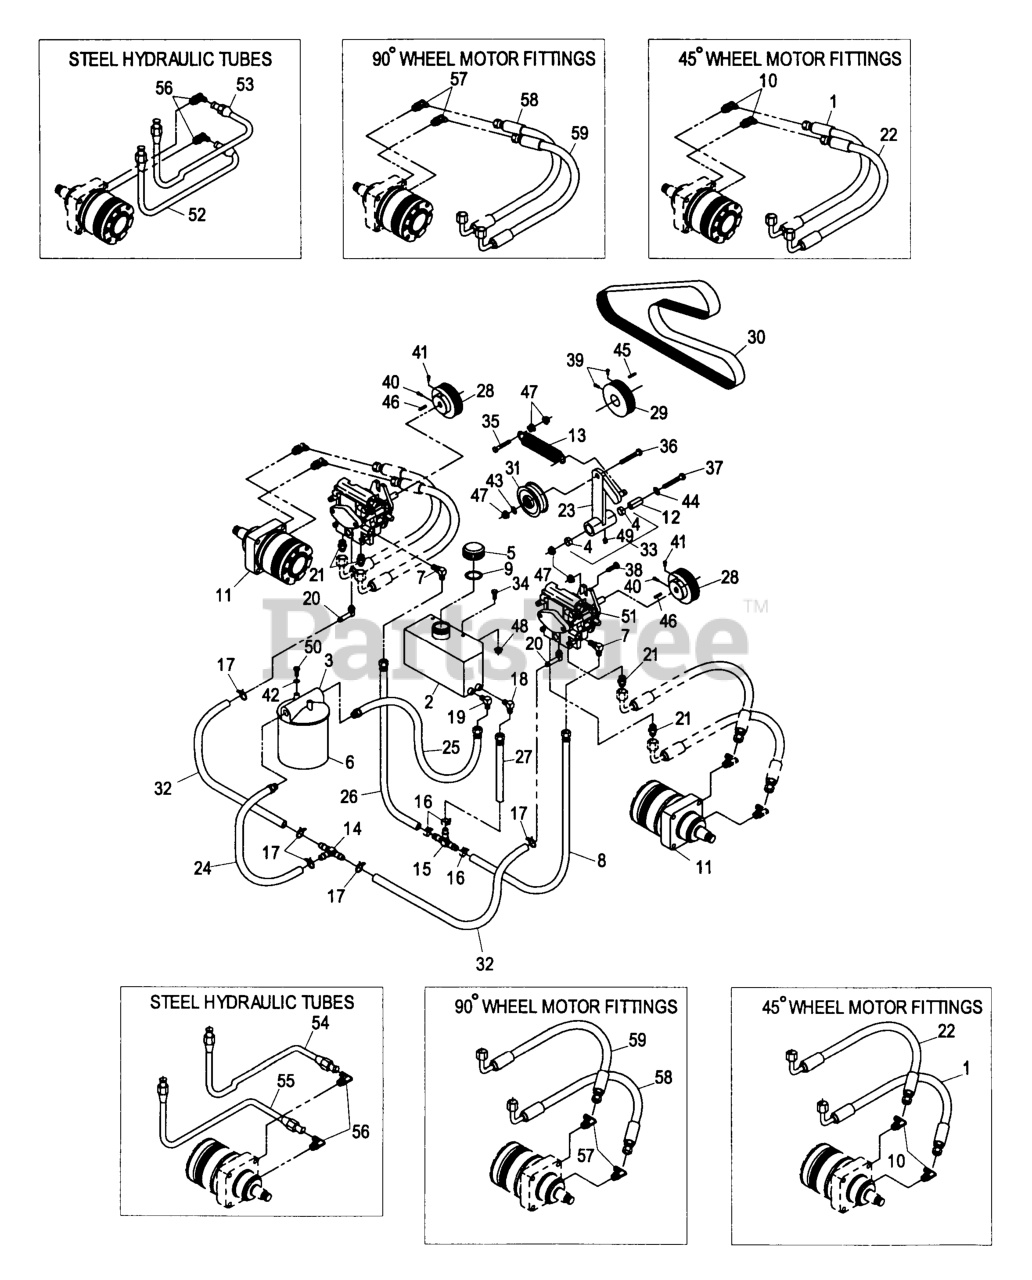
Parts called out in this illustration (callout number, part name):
1	HOSE-PRESSURE, HIGH
3	FILTER-HEAD
4	SLEEVE-BEARING
7	FITTING-90 DEG
8	LOW PRESSURE HOSE ASM
9	GASKET-CAP, TANK
10	FITTING-HYD, 45 DEG
11	MOTOR-WHEEL
12	BUSHING-PIVOT, IDLER
13	SPRING-EXTENSION
14	FITTING-TEE, HOSE
15	FITTING-TEE, HOSE
16	CLAMP-HOSE
17	CLAMP-HOSE
18	FITTING-ELBOW
19	FITTING-ELBOW
20	FITTING
21	FITTING-STRAIGHT
24	HOSE ASM
25	HOSE ASM
26	HOSE ASM
27	HOSE ASM
30	BELT,POLY-V 5K
31	SHEAVE-IDLER
32	HOSE-PRESSURE, LOW
33	BEARING ARM ASM
37	SCREW-HH
39	SCREW-SET
41	SCREW-SET
42	WASHER-LOCK
52	TUBE, RH LOWER 52"
53	TUBE, RH UPPER
54	TUBE, LH UPPER 52"
55	Tube, Lh Lower 52"
56	FITTING-HYD, 90 DEG
57	FITTING-90 DEG
58	HOSE-LOWER
